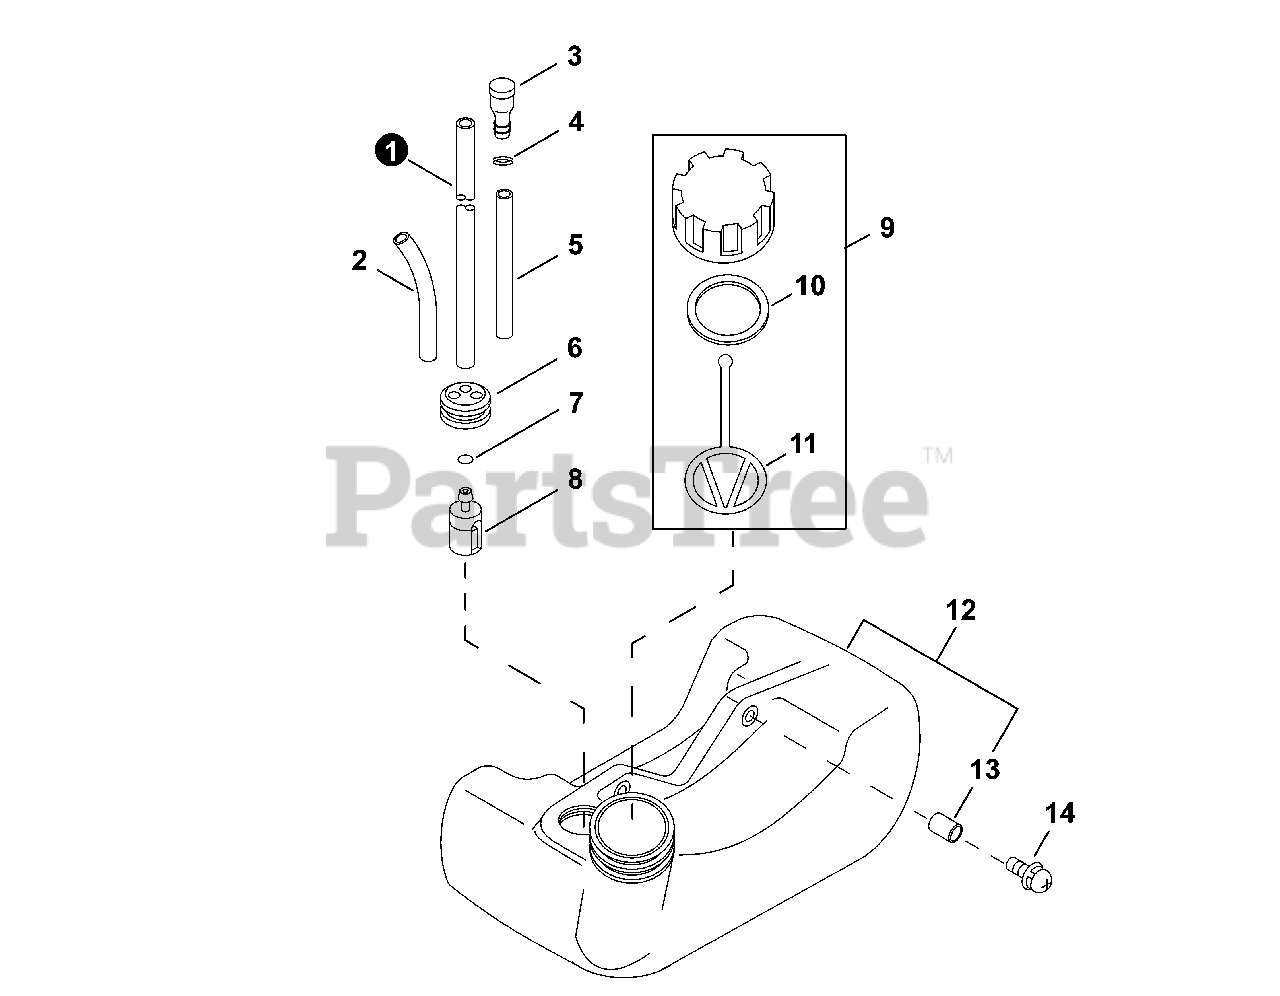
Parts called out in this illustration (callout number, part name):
1	PIPE, FUEL 3×5×180
2	PIPE, FUEL RETURN 3×6×70
3	VENT ASSY
4	CLIP 5.5
5	PIPE, FUEL 3×5×70 BLACK
6	GROMMET, FUEL Ø5
7	CLIP Ø6
8	FILTER, FUEL
9	CAP ASSY, FUEL
10	GASKET, FUEL CAP
11	CONNECTOR, CAP L= 123
12	TANK, FUEL
13	SPACER 6.2×7.8×6
14	SCREW 5×16
